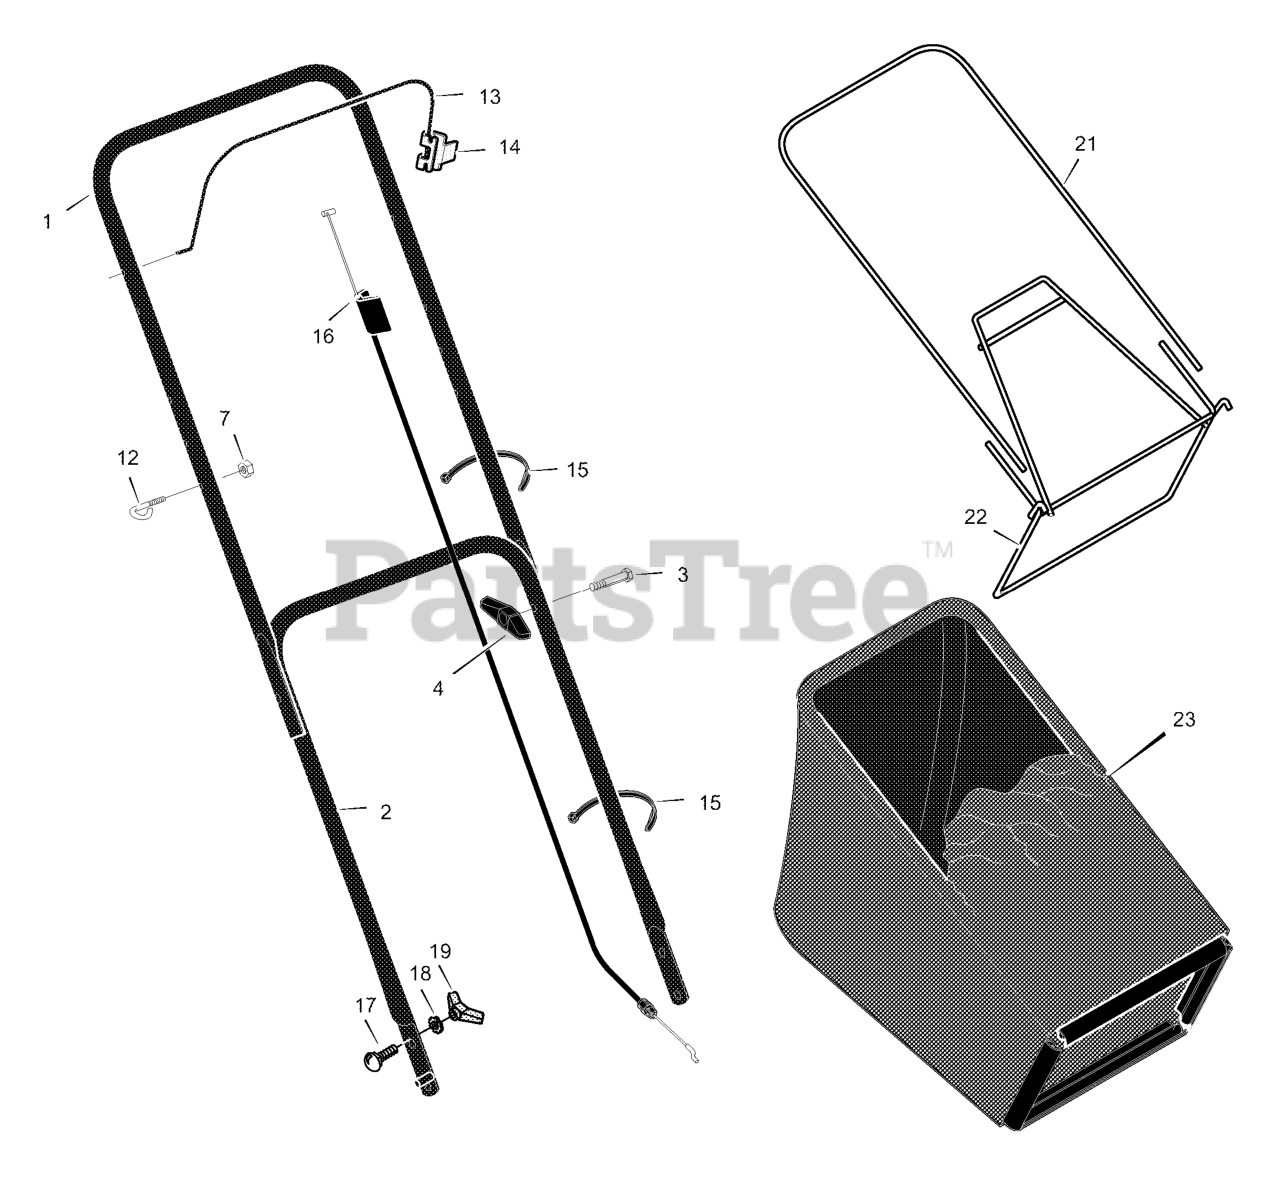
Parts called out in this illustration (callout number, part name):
1	Handle, Upper (Gray)
2	Handle, Lower (Gray)
4	Knob, Plastic
7	Locknut
12	Guide, Rope
13	Engine Stop Lever
14	Bracket, Stop Lever
15	Fastener, Cable
16	Engine Stop Cable
17	Bolt, Carriage
18	Washer
19	Knob, Plastic
21	Frame, Top
22	Frame Assembly
23	Bag, Cloth
